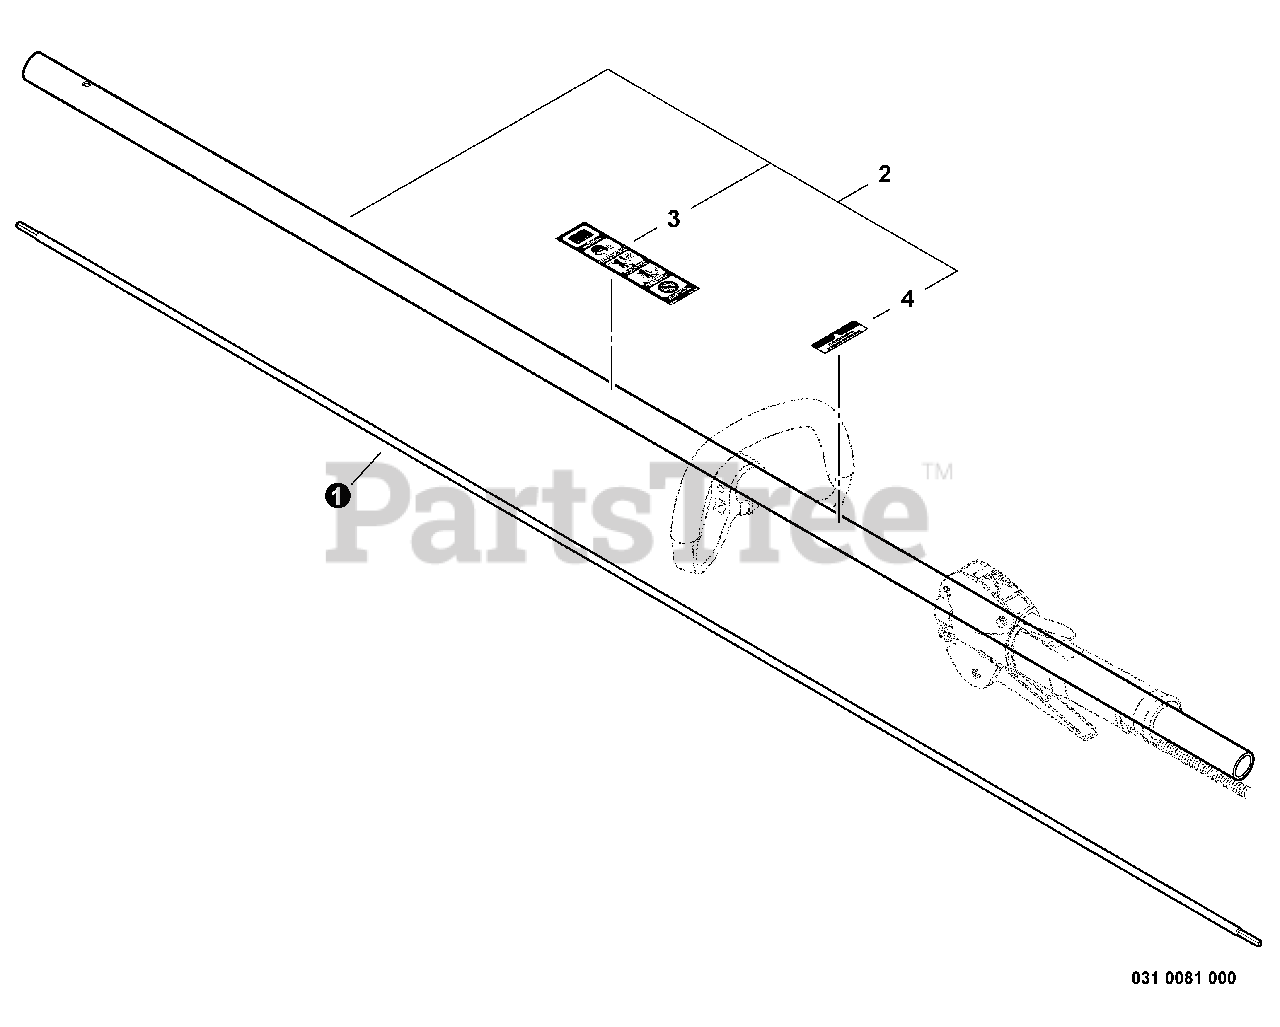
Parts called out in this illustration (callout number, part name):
1	DRIVESHAFT
2	MAIN PIPE ASSY
3	LABEL, CAUTION
4	LABEL, HANDLE
